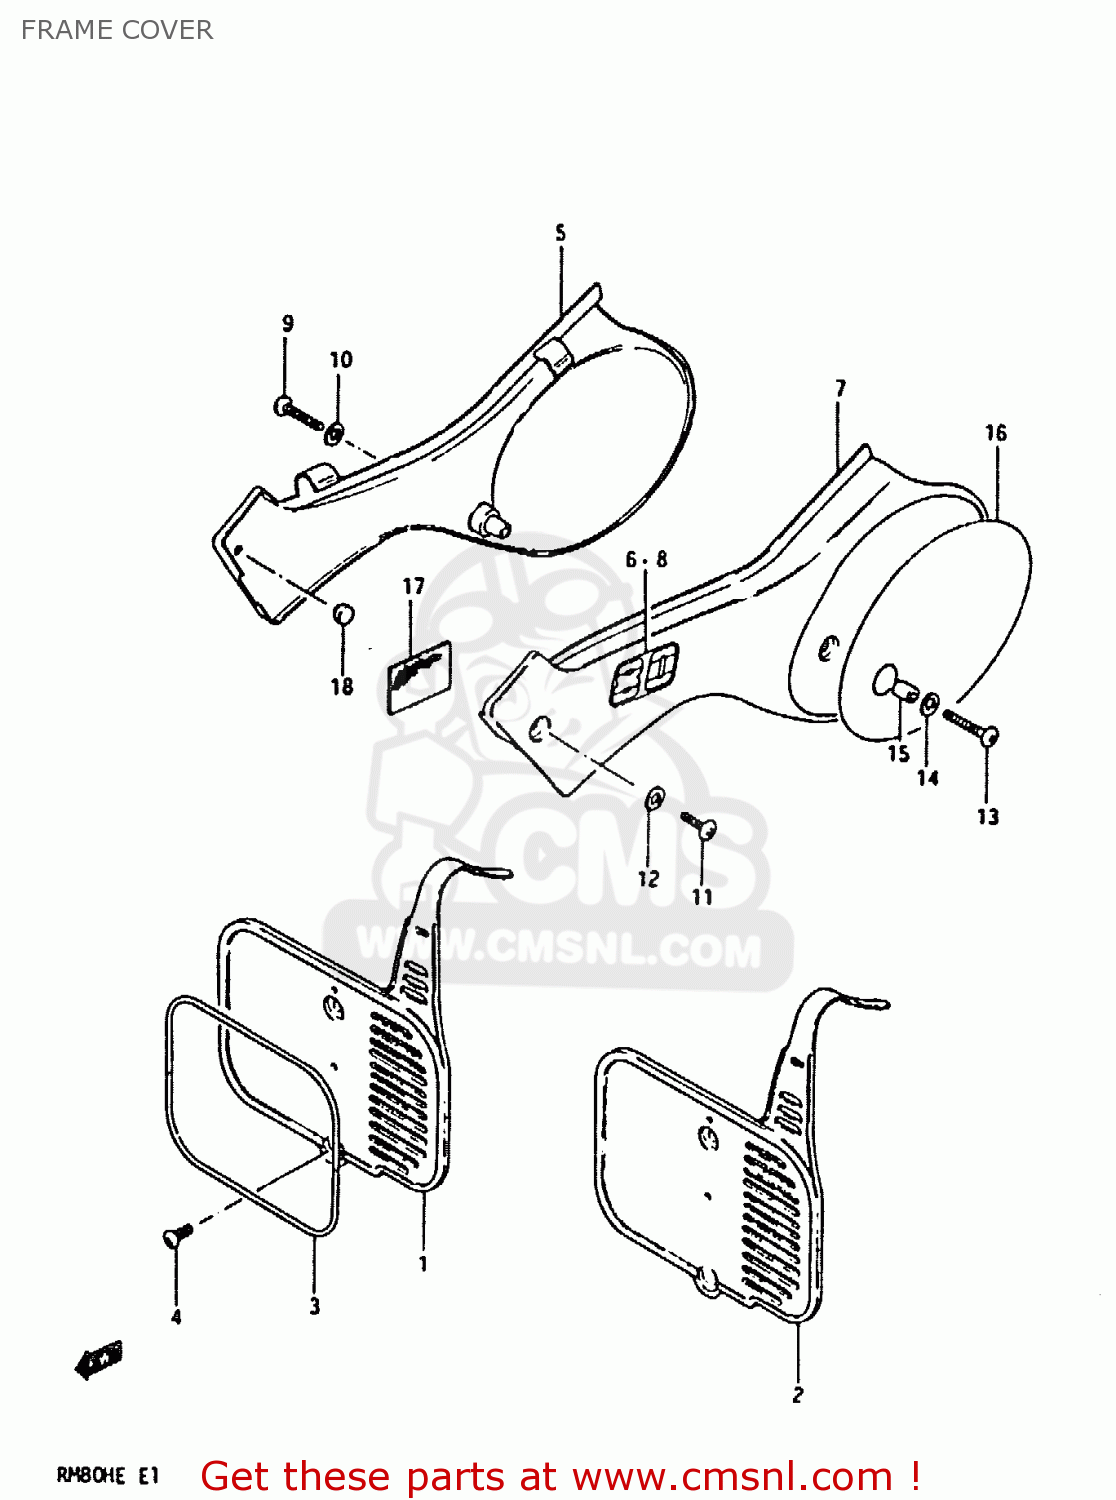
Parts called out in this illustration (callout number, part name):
1	PLATE, FRONT UMBER
2	PLATE, FRONT UMBER
3	EMBLEM
4	SCREW
5	COVER, FRAME RH
6	EMBLEM (80)
7	COVER, FRAME LH
8	EMBLEM (80)
9	SCREW
10	WASHER (6.5X18X1.6)
11	SCREW
12	WASHER
13	SCREW
14	WASHER (6.5X18X1.6)
15	SPACER (6.4X9X20)
16	EMBLEM, LH
17	HEAT SHIELD,FRAME COVER
18	CUSHION
